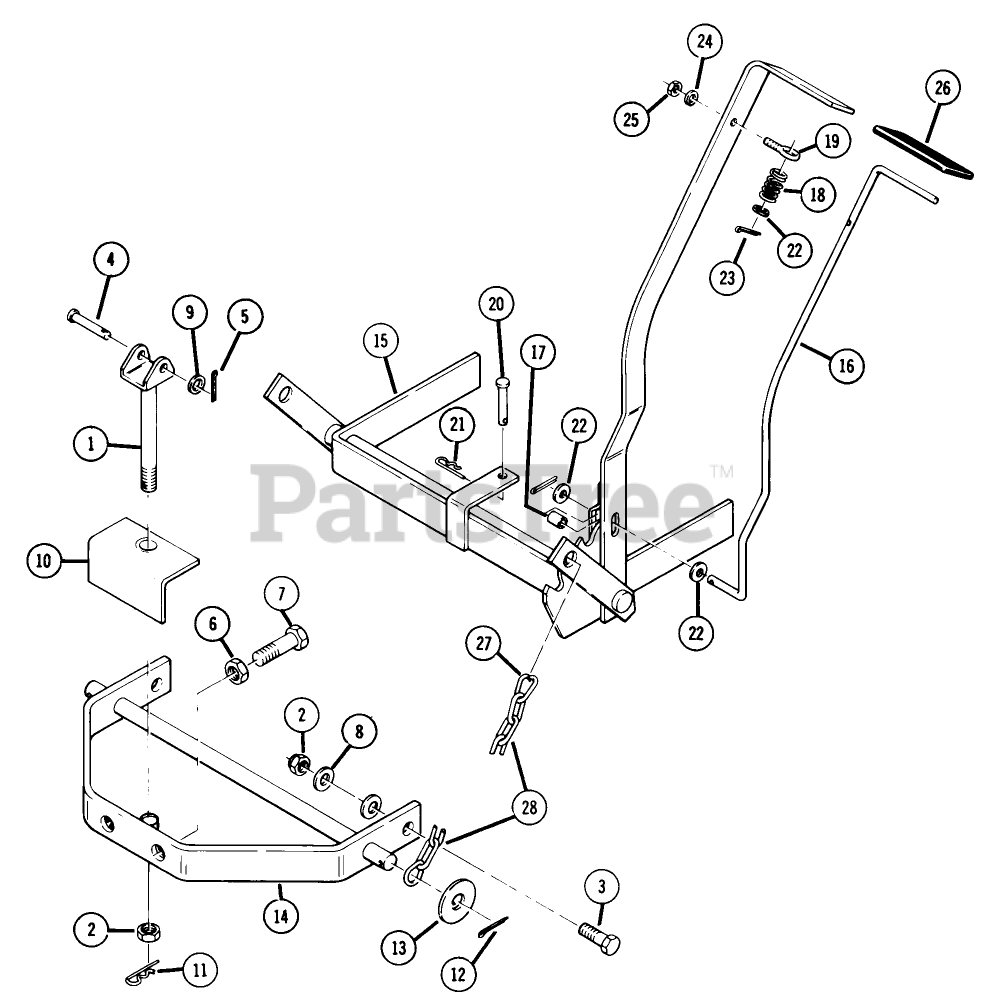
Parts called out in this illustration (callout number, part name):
1	Hitch Pin Assembly
2	Hex Nut 5/8-11
3	Hex Bolt
4	Clevis Pin
5	Cotter Pin
6	Locknut-1/2-13
7	Stabilizer Bolt 1/2-13 x 1 3/8
8	Washer, 1/2
9	Washer .734 OD x .406 ID x .063
10	Stabilizer Plate
11	Hairpin Cotter
12	Cotter Pin 1/8 x 1
13	Washer, STD. 5/8
14	Yoke Assembly
15	Rear Lift Assembly
17	Roller
18	Spring
19	Eye Bolt
20	Clevis Pin
21	Hairpin Cotter
22	Washer
23	Cotter Pin
24	Lockwasher #10
25	Nut #10-32
26	Hand Grip
27	Lap Link
28	Connecting Chain
